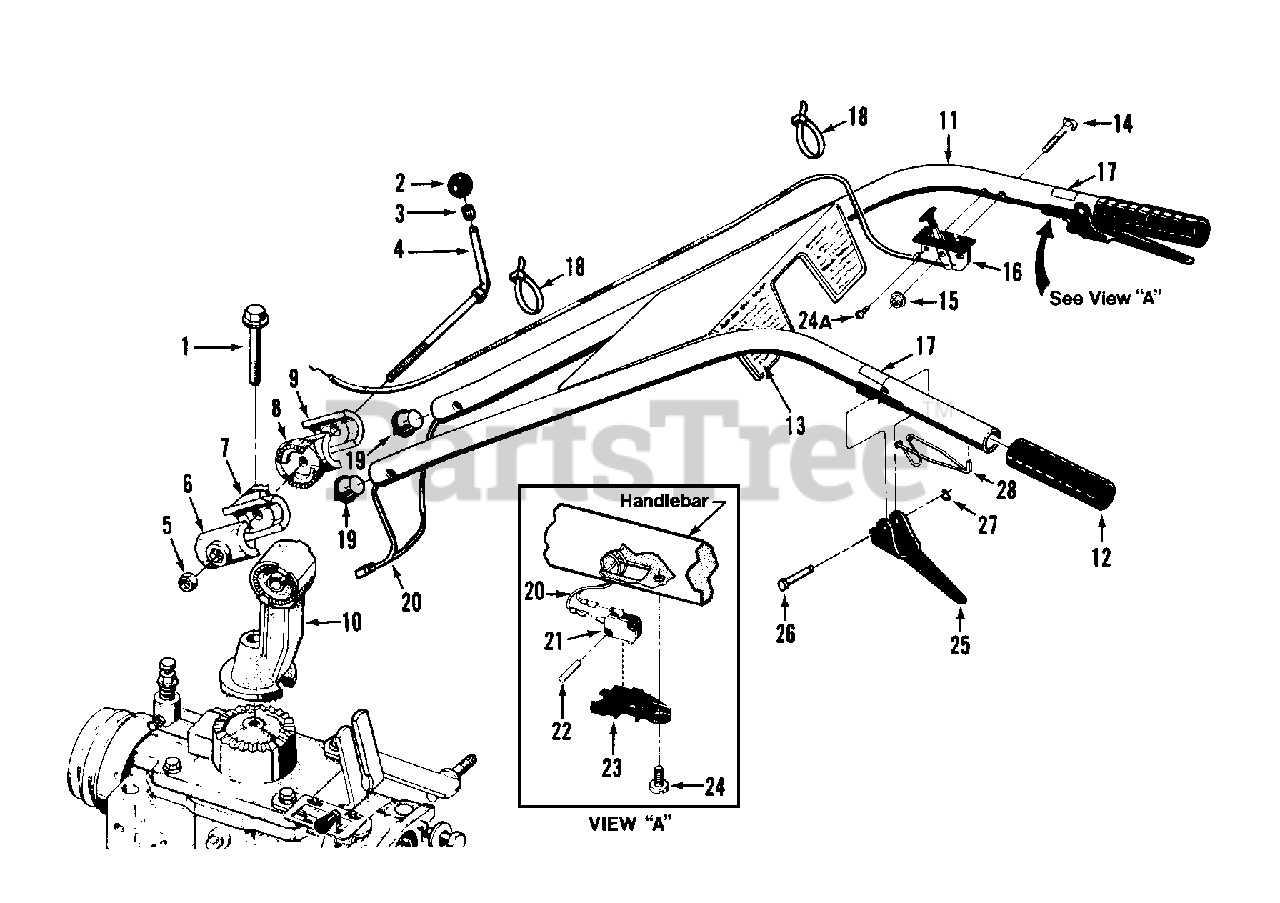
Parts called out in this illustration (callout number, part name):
1	Bolt-Hex hd., flanged self-locking Grade 5, 1/2-13 x 3-1/2"
2	Knob-handlebar height adjustment
3	Ring-retaining (tolerance ring)
4	Stud-handlebar height adjustment
5	Nut-hex, 1/2"-13
6	Clamp-left, handlebar height adjustment
7	Ratchet-left, handlebar height adjustment
8	Ratchet-right, handlebar height adjustment
9	Clamp-right, handlebar height adjustment
10	Base-handlebar mounting
11	Handlebars
12	Grip-handlebars
13	Decal-operator control panel
14	Bolt-curved hd, GR5, 1/4-20 x 2"
15	Nut-hex, flanged self-locking, whiz lock, 1/4"-20
17	Decal-Forward Interlock Lever
18	Tie-plastic
19	Plug-wire harness retainer
20	Handlebar Wire Harness Assy-forward interlock system
21	Handlebar Switch-forward interlock system
22	Lock Pin-handlebar switch
23	Switch Housing-handlebar switch
24	Screw-pan head, 10-24 x 1/2", thread-forming
24A	Screw-phillips head, 10-32 x 1/2", thread-forming
25	Lever-forward interlock
26	Pivot Pin-forward interlock lever
27	Retaining Ring-klip ring-forward interlock lever
28	Return Spring-fwd interlock lever
